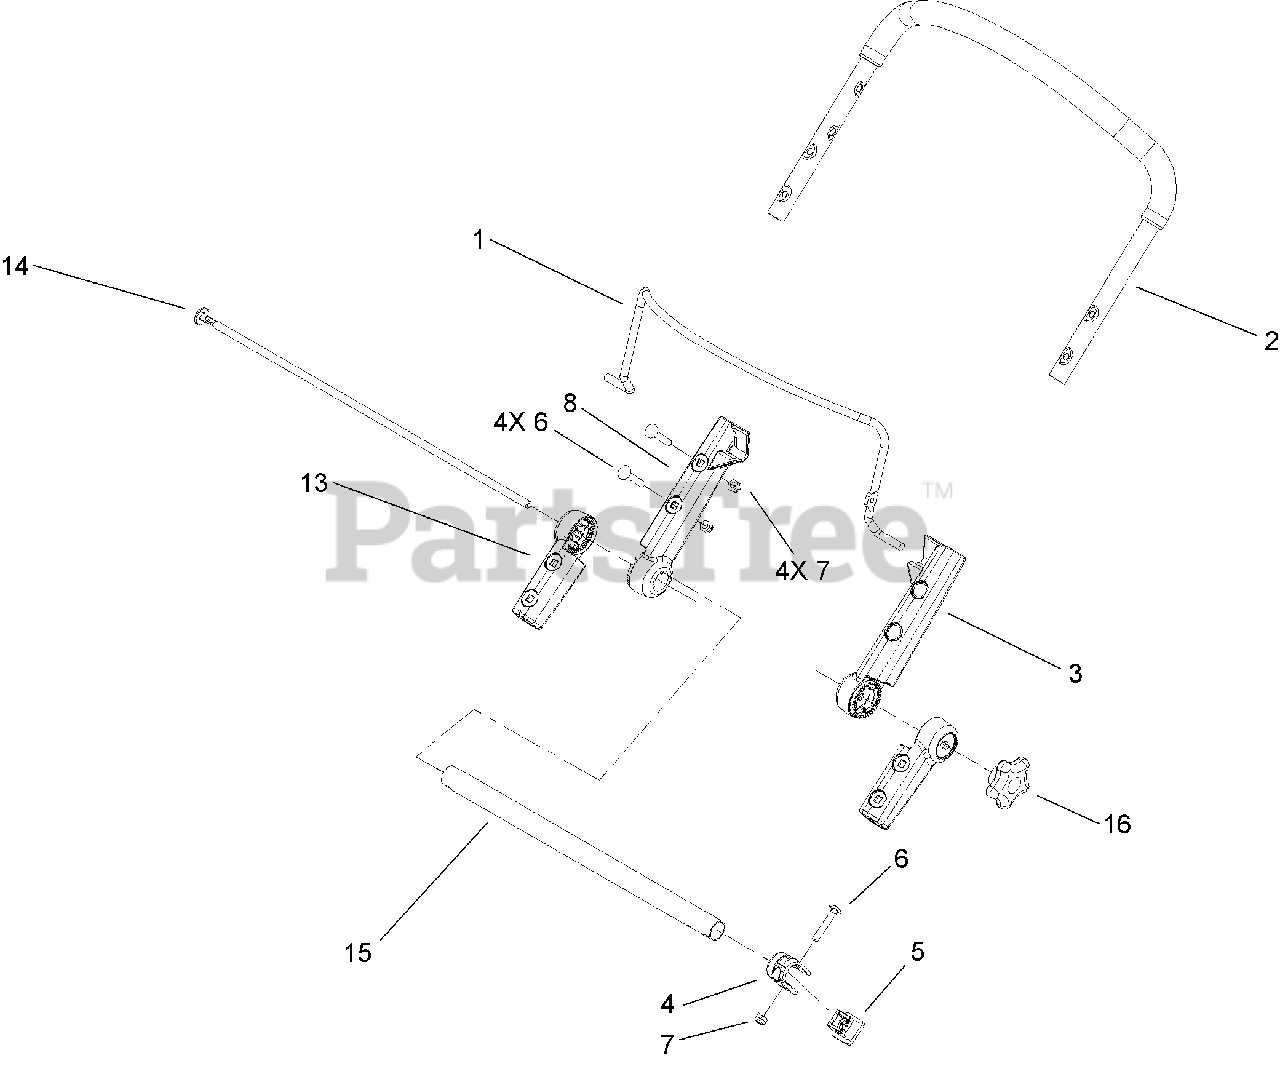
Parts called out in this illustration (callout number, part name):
2	HANDLE ASM
3	MOUNT-HANDLE, LH
4	CABLE-BRAKE
5	SUPPORT-MOUNT, CABLE
6	SCREW-CARR
7	NUT-LOCK, NI
8	MOUNT-HANDLE, RH
13	MOUNT-HANDLE, LOWER
14	ROD-THREADED
